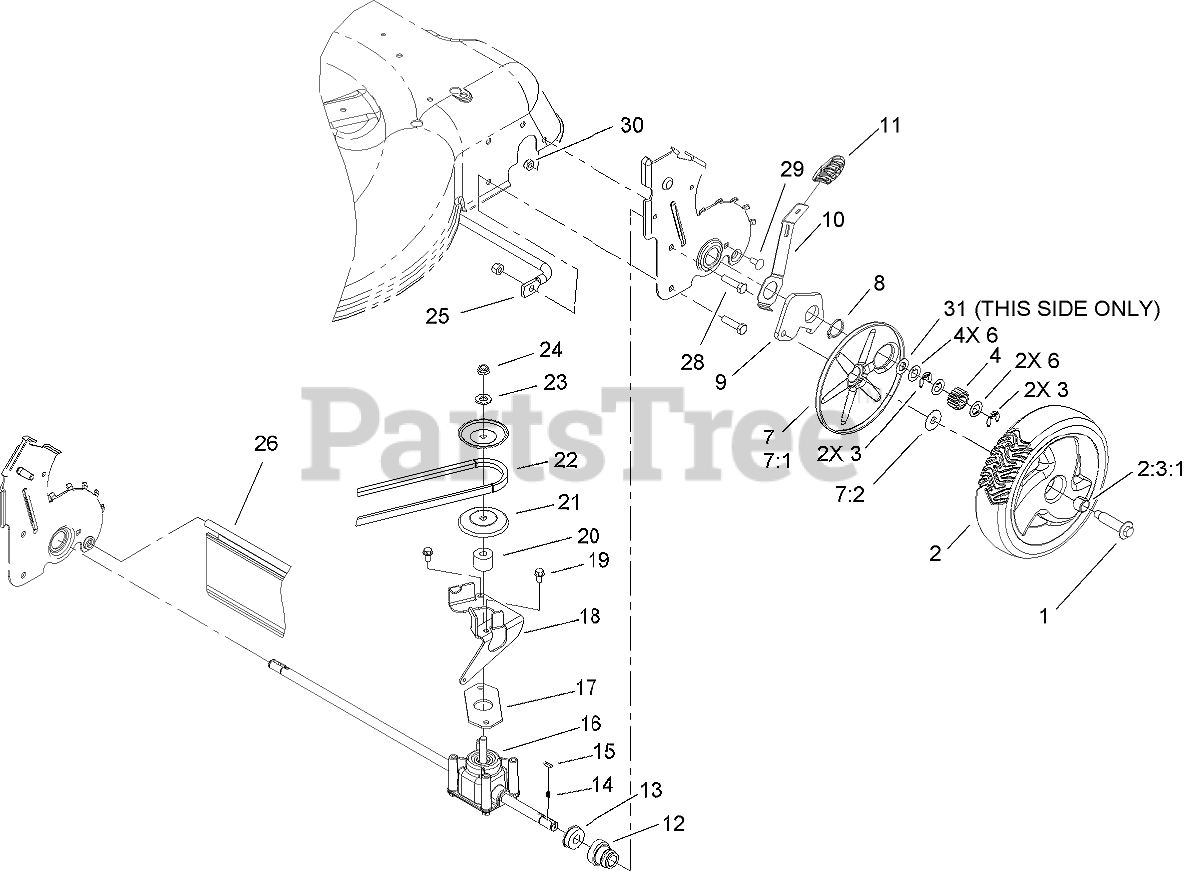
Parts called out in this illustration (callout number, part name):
1	BOLT-SHOULDER
2	Wheel Gear ASM
2:3	Wheel ASM
2:3:1	BUSHING
3	RING-CLIP, LOCKING
4	Gear-Pinion, 15t
6	Washer-Thrust
7	WHEEL COVER ASM
7:1	COVER-WHEEL
7:2	WASHER-STEPPED
8	RING-RETAINING
9	Arm-Pivot, Rear (LH)
10	Arm-Spring
11	Knob-Lever, HOC
12	RETAINER-BEARING, HOC
13	BEARING-BALL
14	SPRING-COMPRESSION
16	TRANSMISSION ASM
17	GASKET-GEARBOX
18	BRACKET-PIVOT
19	SCREW-HWH
20	SPACER
21	PULLEY-HALF
22	BELT-V
23	WASHER-FLAT
24	NUT-HEX
25	BRACE-PLATE, HOC
26	SHIELD-TRAILING
28	SCREW-HH
29	SCREW-CARR
30	NUT-LOCK, NI
31	WASHER-PLAIN
